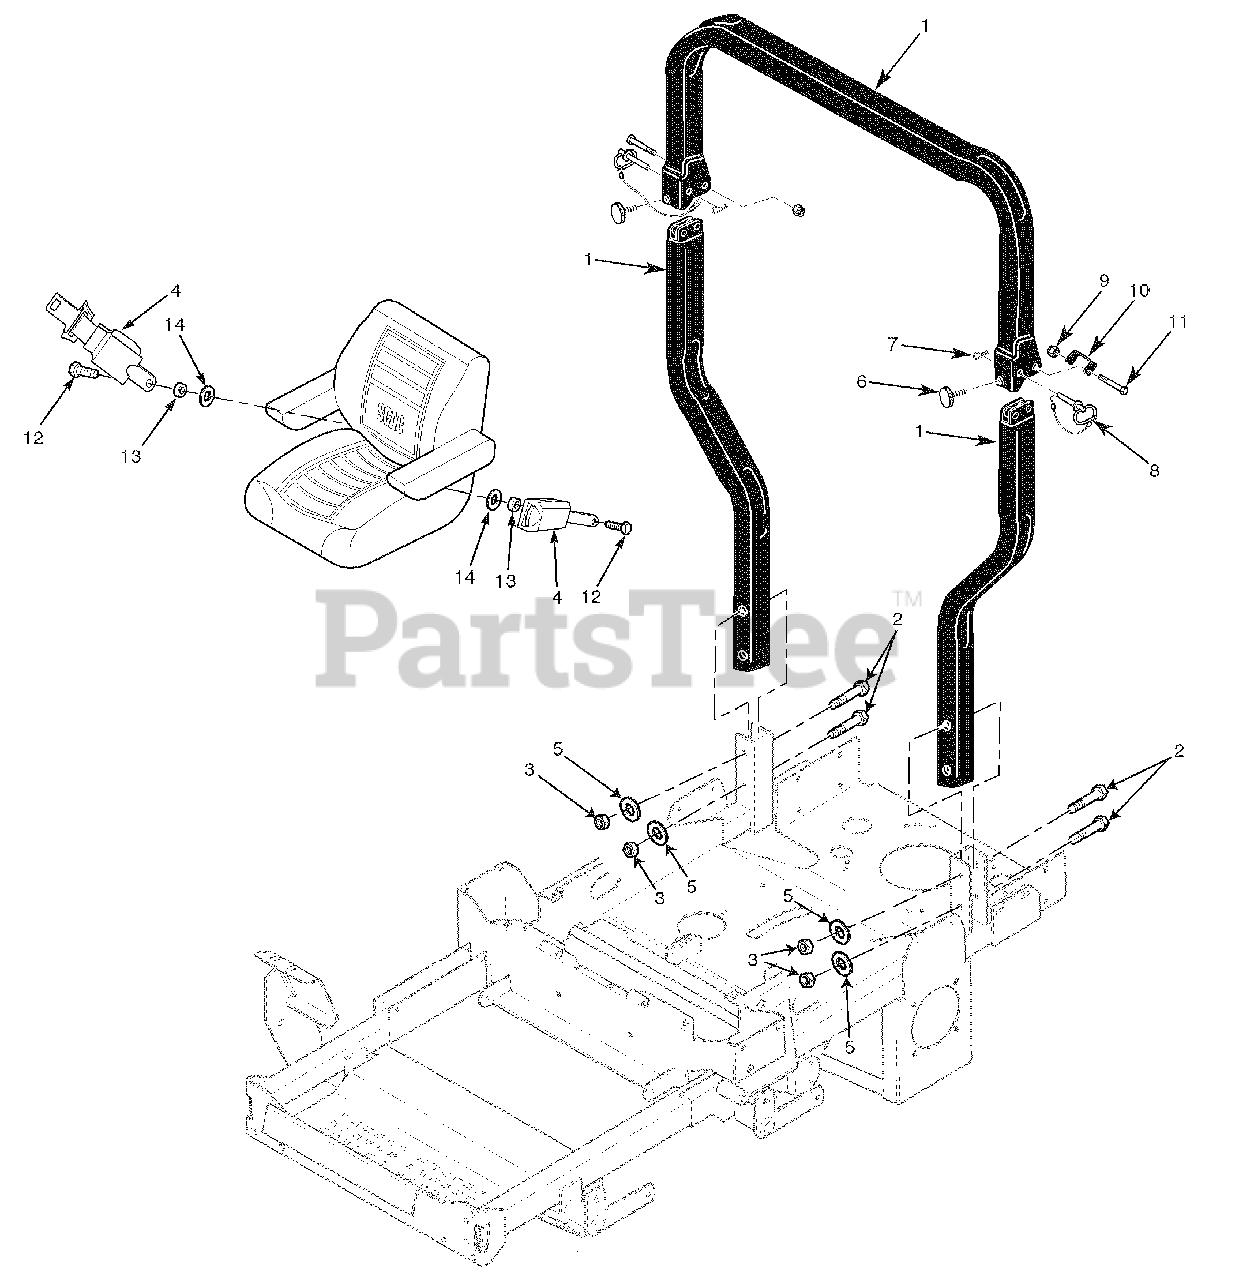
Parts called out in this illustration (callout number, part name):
1	STC Foldable ROPS
2	Bolt, Hex Head 1/2-13 x 3-1/2"
3	Nut, Center Lock 1/2-13
4	Retractable Seat Belt
5	Flatwasher, 1/2-.562 x 1.375 x .109
6	Thumb Screw, 5/16-18 NC x 3/4"
7	Hair Pin, Cotter
8	Pin
9	Nut, Center Lock 1/2-13
10	Bracket, Stop
11	Bolt, Hex Head 1/2-13 x 3-1/2"
12	Bolt, Hex Head 7/16-20 x 1"
13	Spacer
14	Flatwasher, 7/16-.500 x 1.25 x .083
